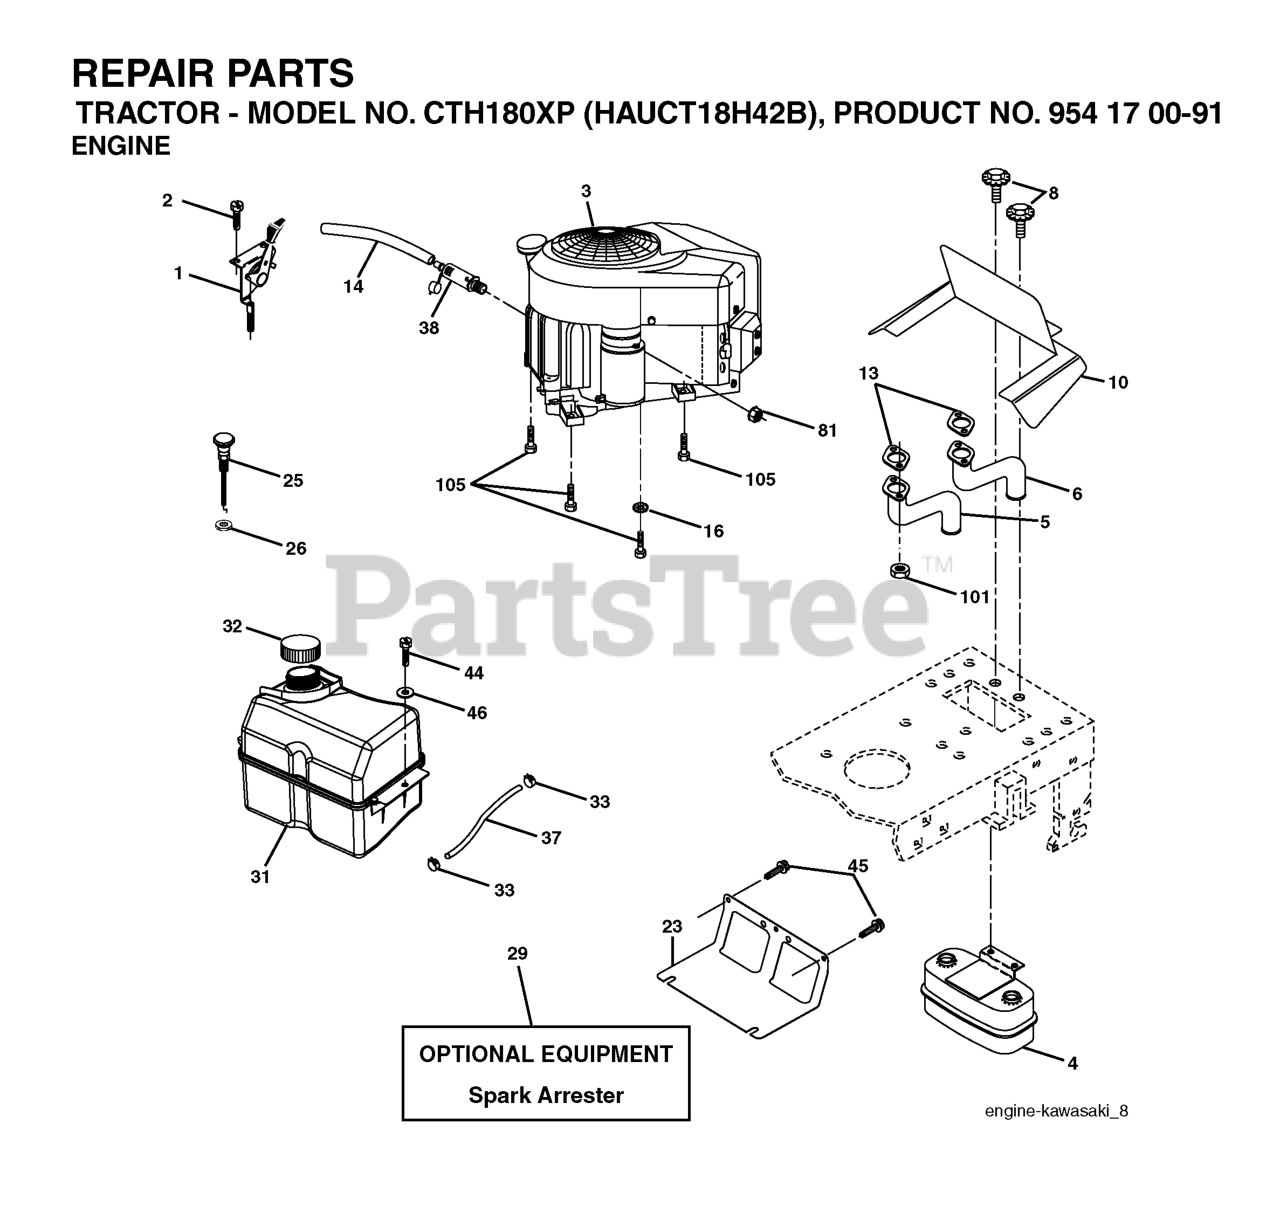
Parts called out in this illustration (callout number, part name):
1	CONTROL, THROTTLE
2	SCREW
4	MUFFLER.TWIN.CYL.LOW.TONE
5	EXHAUST.TUBE.LH.KAWASAKI.
8	BOLT.5/16-18UNCX3/4 W/SEMS.BLK
10	RP SHIELD HEAT MUFFLER
14	TUBE, DRAIN OIL ASM.
16	LOCKWASHER
23	SHIELD.BROWNING.DBR.GUARD
25	CHOKE CONTROL
26	Nut Keps 3/8 - 24 UNF
29	KIT.SPARK ARRESTOR 794945 B&S
31	FUEL TANK
32	FUEL CAP
33	HOSE CLAMP
37	LINE.FUEL.20
40	BUSHING.SNAP.NYL.BLK.
41	STEM FUEL TANK
44	SCREW HEXWSHR 1/4-20X3/4
45	SCREW, 3/8-16X3/4
81	NUT
101	NUT.HEX.FLANGE.TOPLOCK
105	SCREW 3/8-16X1
112	BUSHING OUTLET T
